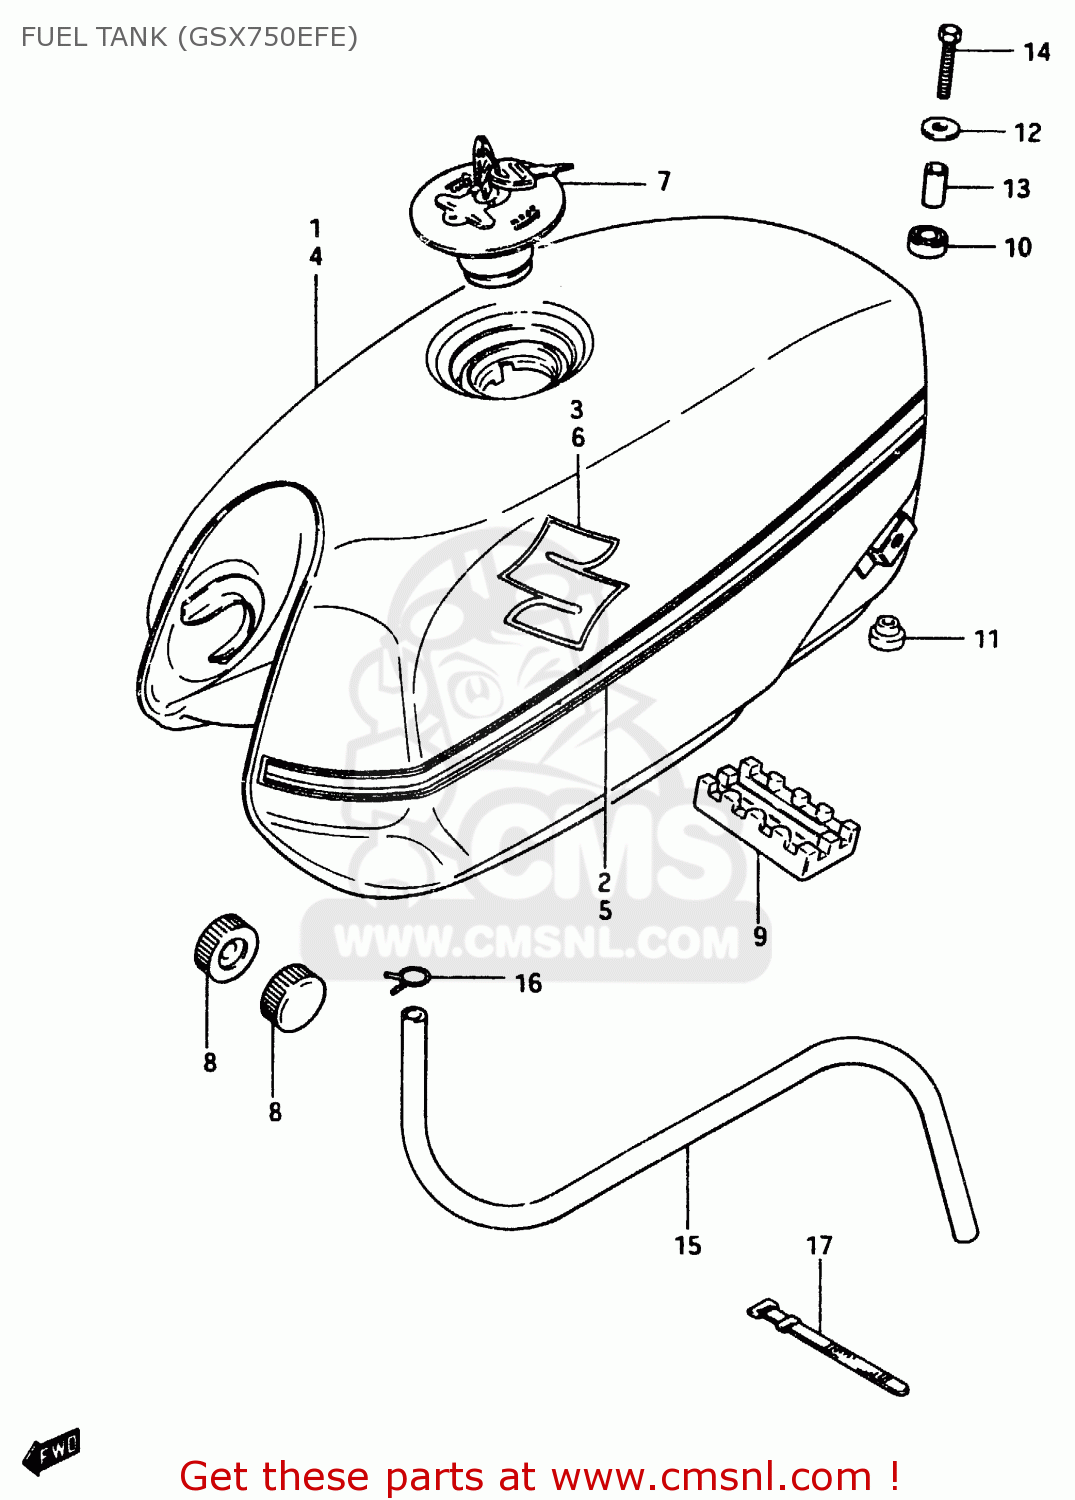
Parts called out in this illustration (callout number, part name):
1	TANK, FUEL
2	TAPE SET, FUEL TANK
3	EMBLEM
4	TANK, FUEL
5	TAPE SET, FUEL TANK
6	EMBLEM
7	CAP, FILLER
8	CUSHION
9	CUSHION,FUEL TANK CTR
10	CUSHION
11	CUSHION
12	WASHER (6.5X24X1.6)
13	SPACER
14	BOLT
15	HOSE,FUEL
16	CLIP
17	CLAMP(L:187)
